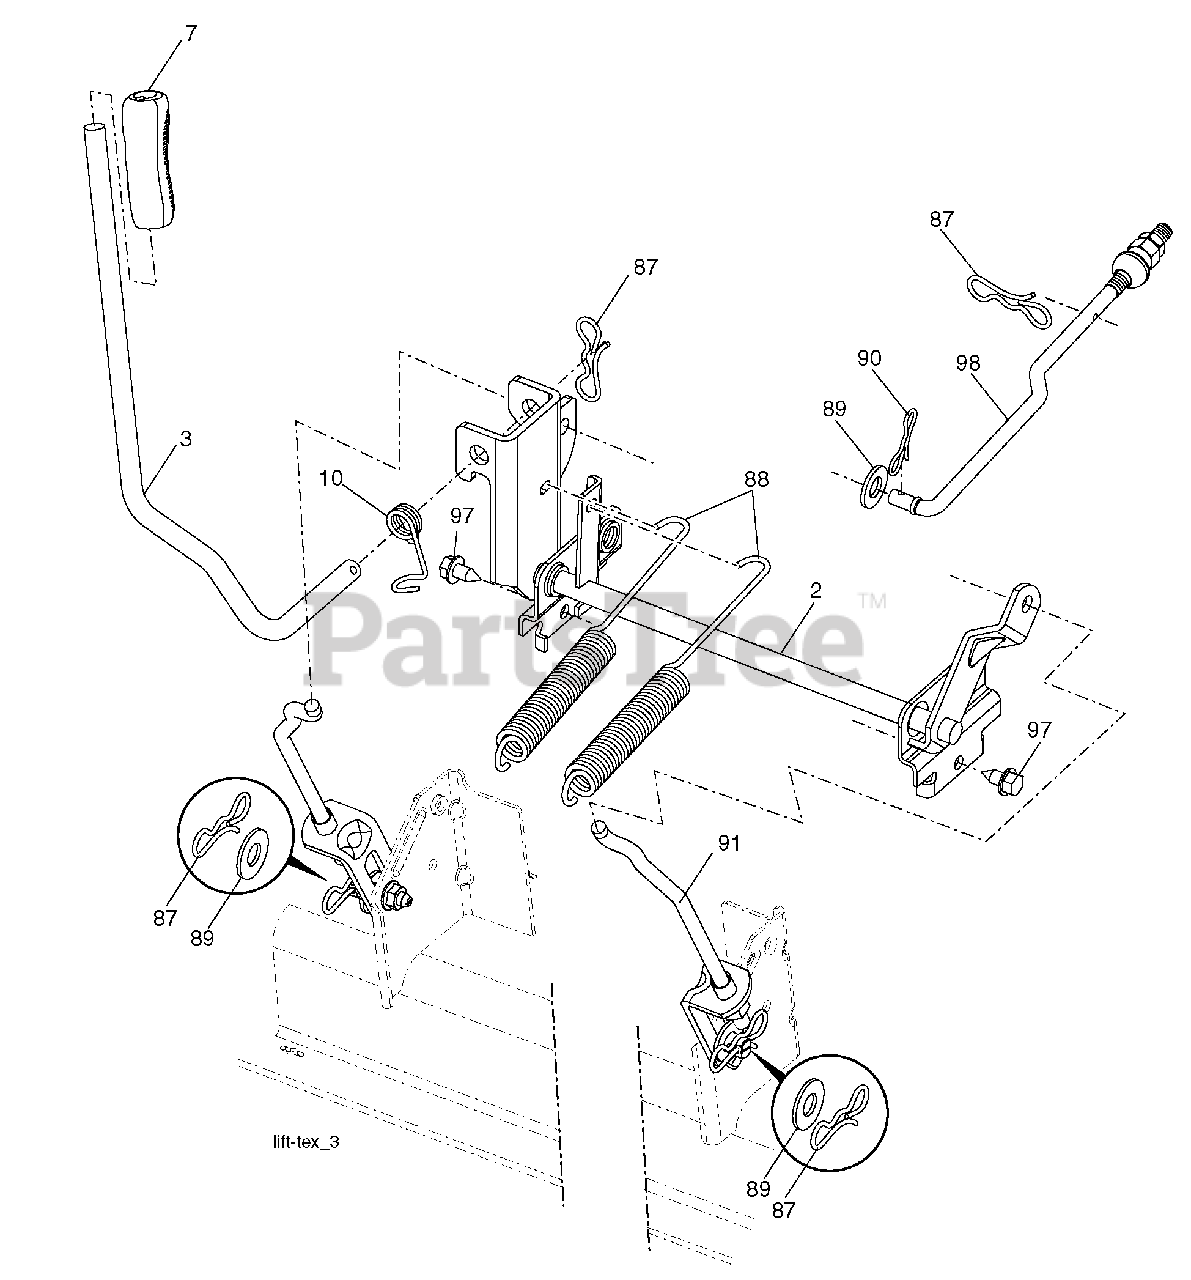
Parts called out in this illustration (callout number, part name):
2	Shaft Asm., Lift
3	Lever Asm., Lift Rh
7	Grip, Lever
10	Spring Torsion
87	Pin Cotter 7/16 Bow Tie Lock
88	Spring Lift Assist
89	Washer Clear Zinc
90	Pin Cotter 5/16 Bow Tie Lock
91	Link Lift Susp Mower Rear
97	Screw 3/8-16 x .75 Smgml Tap/R.Z
98	Link Lift Susp. Front Mower
